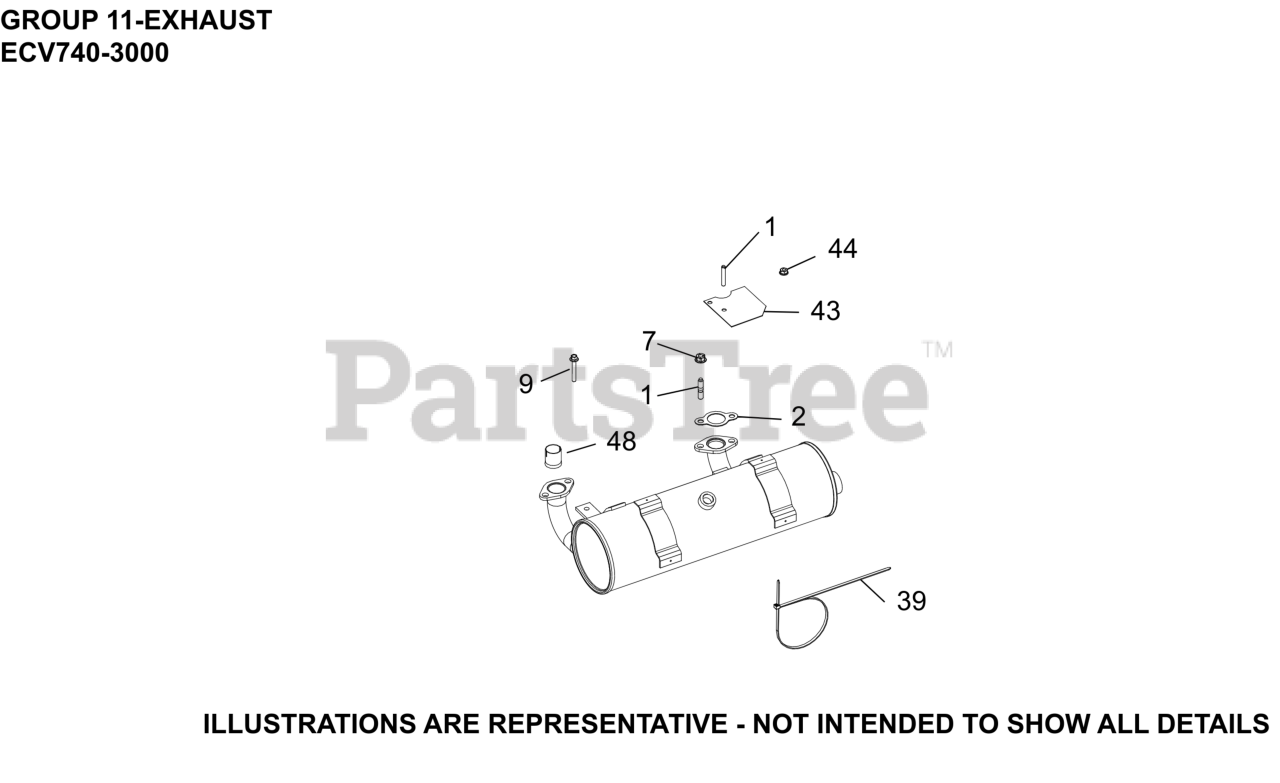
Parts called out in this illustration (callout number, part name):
1	STUD, M6X1.0X36
1	STUD, METRIC EXHAUST
2	GASKET, EXHAUST MANIFOLD
7	NUT, HEX FLANGE LOCK (M8)
9	SCREW, FLG M6X1.0X40
43	DEFLECTOR, HEAT
44	NUT, FLG M6X1.0
48	LINER, EXHAUST PORT
NI	BRACKET, MAIN SUPPORT
NI	SENSOR, OXYGEN (M12 x 1.25 THREADS)
